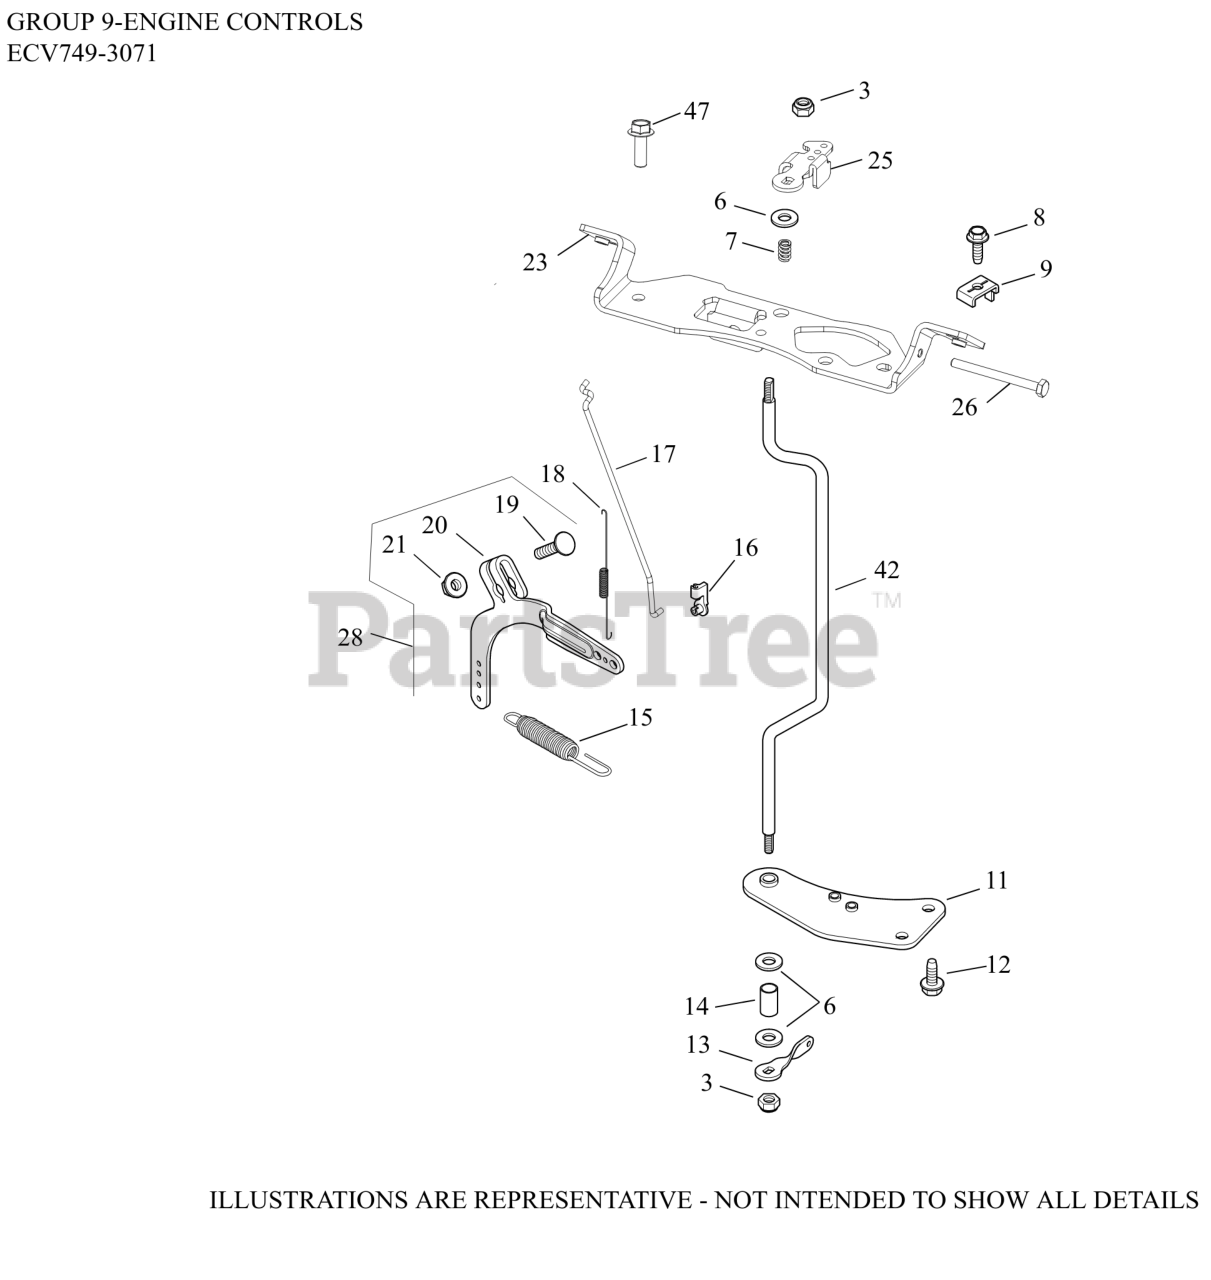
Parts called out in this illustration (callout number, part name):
3	NUT, LOCK M6X1.0
6	WASHER, FLAT 1/4"
7	SPRING, THROTTLE SHAFT
8	SCREW, THREAD FORMING
9	CLAMP, CABLE CABLE
11	BRACKET, THROTTLE SHAFT
12	SCREW, THREAD FORMING
13	LEVER, THROTTLE CONTROL
15	SPRING, GOVERNOR (BLUE)
16	BUSHING, THROTTLE LINKAGE
17	LINKAGE, THROTTLE
18	SPRING, LINKAGE
19	BOLT, RD HD SQ NECK M6X1.0X25
20	LEVER, GOVERNOR - (#2409069S)
21	NUT, FLG M6X1.0
23	BRACKET, CONTROL
25	LEVER, THROTTLE CONTROL
26	SCREW, HEX HEAD
28	LEVER, GOVERNOR ASSEMBLY
42	THROTTLE CONTROL SHAFT
47	SCREW, HI-LOW
